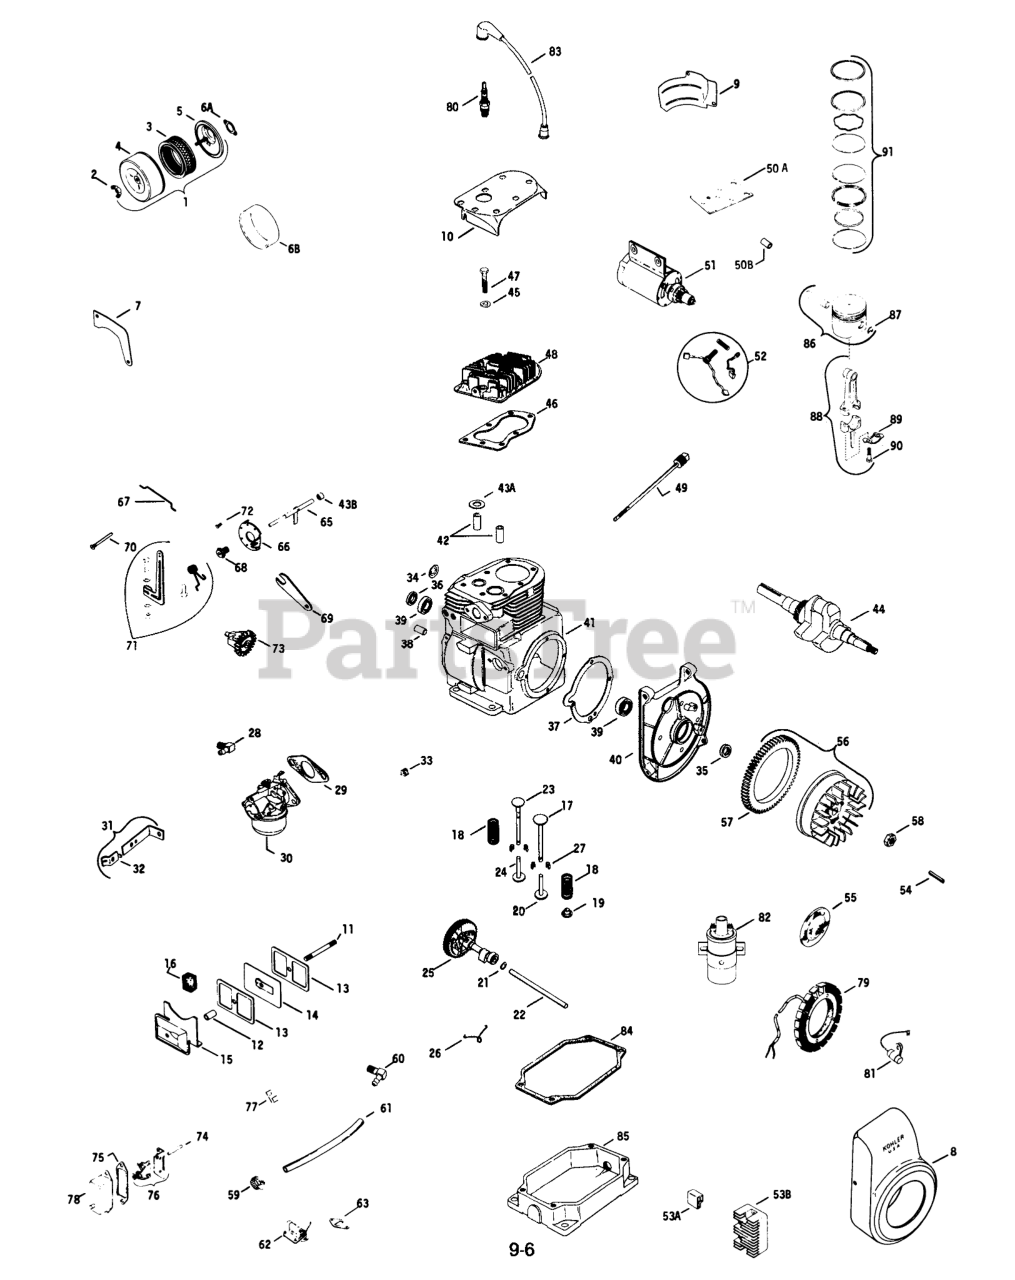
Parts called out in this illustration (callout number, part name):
1	Cleaner, air-assembly
2	Nut-Wing
3	Element, Air Cleaner
4	Valve-Needle, Float
5	Base, Air Cleaner
6A	Gasket
6B	Element, Pre-Cleaner
7	Baffle side air
8	Housing, blower
9	Baffle cylinder
10	Baffle, Head
11	Stud valve cover
12	Seal
13	Gasket-Valve Cover
14	Breather
15	Cover, Valve
16	Filter
17	Valve-Intake
18	Spring, Valve
19	Retainer-Spring
20	Tappet, intake valve
21	Spacer camshaft .005
21	Spacer, Camshaft.010
22	Pin, Camshaft
23	Valve, exhaust
24	Tappet-Exhaust Valve
25	Kit, camshaft
26	Spring-Actuating
27	Keeper, Valve
28	Elbow
29	Gasket-Carburetor
30	Carburetor-assembly
31	Bracket, choke
32	Clip
33	Plug
34	Plug
35	Seal Front Oil
36	Seal Rear Oil
37	Gasket
38	Pin-Dowel
39	Ball Bearing
40	Plate, Bearing
41	Block, cylinder - assembly (Use B-234989 Miniblock)
42	Guide-Valve
43A	Insert
43B	Bearing
44	Crankshaft
45	Washer
46	Gasket, head
47	Screw, H.C. 5/16-18 x 1-1/2
48	Head, Cylinder
49	Dipstick
50A	Bracket, coil
50B	Spacer
51	Starter
52	Kit, Brush & Spring
53A	Connector
53B	Regulator
54	Key
55	Screen, grass
56	Flywheel
57	Gear Ring
58	Nut
59	Clamp
60	Elbow
61	Line, Fuel
62	Pump, fuel
63	Gasket, pump
65	Shaft-Governor Cross
66	Disc, regulating
67	Link-Governor
68	Bushing Governor
69	Bracket, speed control
70	Pin-GovemorStop
71	Lever, Governor
72	Pin
73	Gear, Governor
74	Rod, Breaker
75	Gasket, Cover
76	Breaker
77	Clip
78	Cover breaker
79	Stator
80	Spark plug
81	Condenser
82	Coil
83	Kit, Hi-Tension
84	Gasket, pan
85	Pan, oil
86	Piston - assembly--Std. (Includes pin & retainers)
87	Retainer, Pin
88	Rod, Connecting Std.
89	Lock, Conn. Rod
90	90A9-5/66734 SENSAT
91	Ring set-Std. & .003 (Service)
